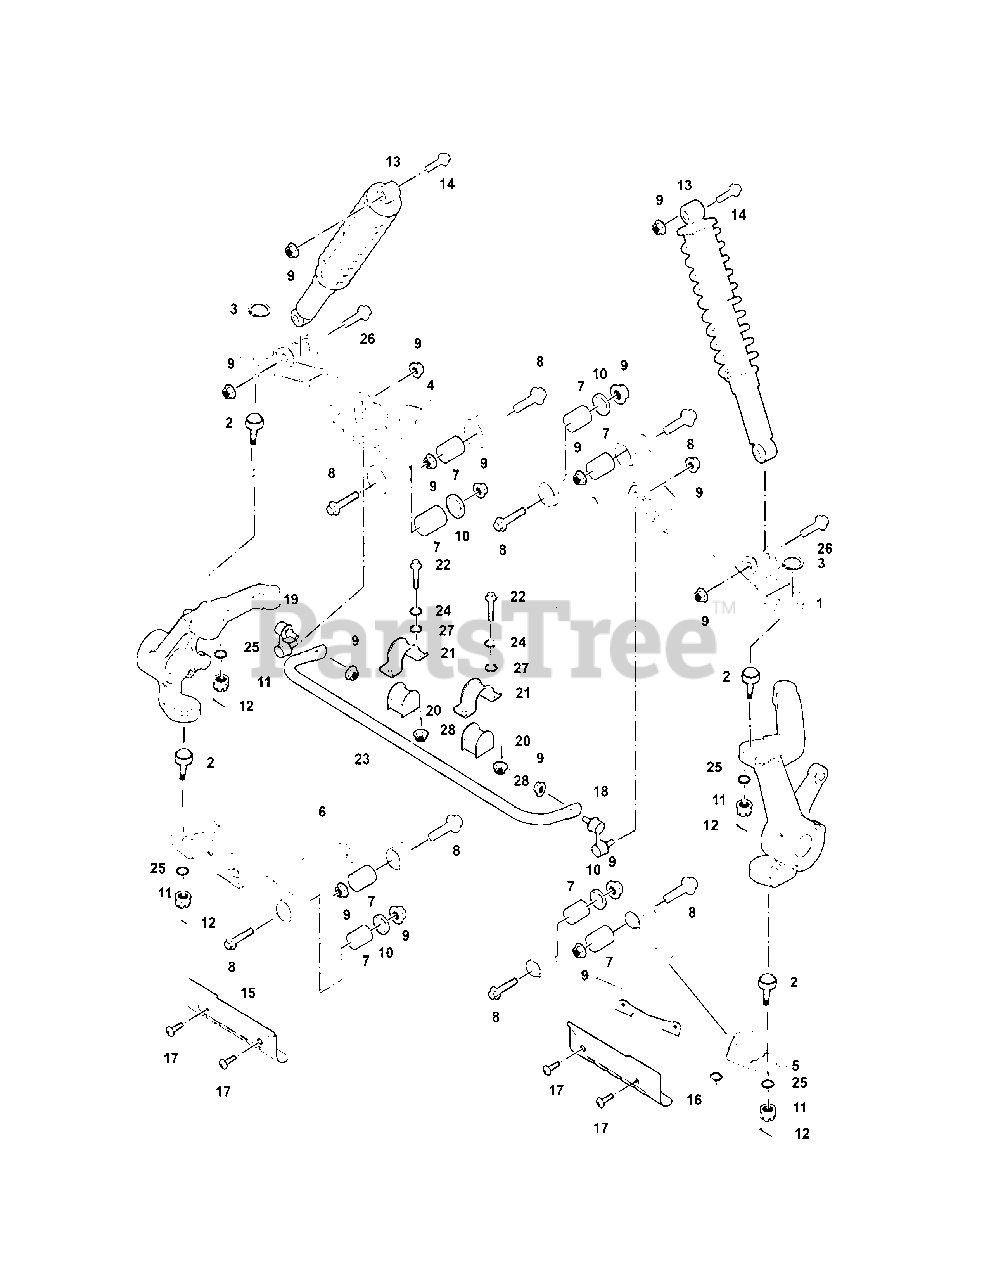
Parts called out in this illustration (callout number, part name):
1	Left front upper swing arm
2	Joint A, suspension
3	Circlip D0=30
4	Right front upper swing arm
5	Left front lower swing arm
6	Right front lower swing arm
7	Bushing 10×23×50
8	Bolt M10×1.25×78
9	Hexagon flange nut M10×1.25
10	Nylon Bushing
11	Hexagon nut M12×1.25
13	Front shock absorber
14	Bolt M10×1.25×60
15	Protective Board, Rear Right Lower Swing Arm
16	Protective Board, Rear Left Lower Swing Arm
17	Cross large plate head screw M6×16
18	Left Tie-Rod, Anti-Roll Bar
19	Right Tie-Rod, Anti-Roll Bar
20	U-type Rubber bush III
21	Press Block, Rear Anti-Roll Bar
22	Hexagon Flange Bolt M8×22
23	Front anti-roll bar
24	Spring Washer -8
25	Spring Washer -12
26	Bolt M10×1.25×60
27	Cushion 8.4×16×1.6
27	Hexagon Flange Lock Nut M8 (Metallic Insert)
28	Hexagon Flange Lock Nut M8 (Metallic Insert)
